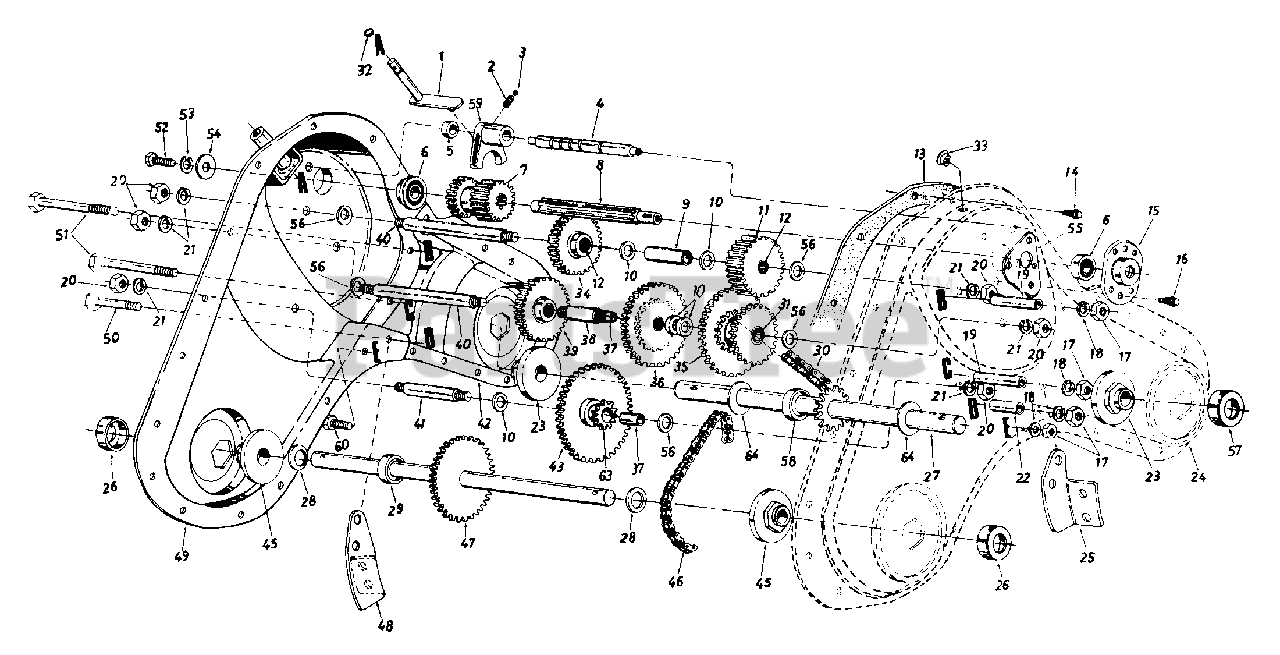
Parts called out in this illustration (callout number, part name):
1	Shifting Bracket Ass'y.
2	Compression Spring .50" Lg.
3	Ball Detent .250" Dia.
4	Detent Shaft 1/2" Dia.
5	Spacer .505" I.D. x .88" O.D.
6	Ball Brg. .62" I.D. x 1.38"
7	Spur Gear 16T (Input)
8	Input Spline Shaft 7/8"
9	Spacer .657" I.D. x 2.85" Lg.
10	Fl-Wash. .640" I.D. x 1.24"
11	Spur Gear 30T 7/8" I.D.
12	Needle Bearing 5/8" I.D.
13	Gasket - Trans. Hsg.
14	Hex S-Tap Scr. 1/4-20 x .5"
15	1-3/8" Dia. Bearing Housing
16	Hex TT-Tap Scr. 1/4-20 x .75"
17	Hex Nut 5/16-18 Thd.
18	L-Wash. 5/16" I.D.
19	Spacer 1.56" Lg.
20	Hex Nut 7/16-20 Thd.
21	Bell-Wash. .45" I.D. x 1.0"
22	Spacer 1.015" Lg.
23	Tine Shaft Brg. 1.002 x 2.50
24	Trans. Housing Ass'y. - L.H.
27	Tine Shaft Ass'y. 1" O.D.
28	Fl-Wash. .76" I.D. x 1.5" O.D.
29	Spacer .75" I.D. x .50" Lg.
30	Chain #50 5/8 Pitch x 52 Links - Endless
31	Needle Bearing 5/8" I.D.
32	Snap Ring
33	Taper Cap Plug
34	Spur Gear 30T 12/16" I.D.
35	30/44T Gear Ass'y. Comp.
36	Spur Gear 44T
37	Sleeve Bearing
38	Gear Hub 3/4" I.D. x 3" Lg.
39	Spur Gear 30T 1.0" I.D. x 1/2" W
40	Jack Shaft 5/8" Dia. x 5"
41	Jack Shaft 5/8" Dia. x 2.38"
42	Trans. Housing Ass'y. - R.H.
43	Spur Gear 55T
45	Wheel Brg. .752" x 2.5"
46	#420 Chain 1/2 Pitch x 50 Links - Endless
47	Wheel Shaft Ass'y. 15.6"
51	Hex Bolt 5/16-18 x 2.5"
52	Hex Bolt 1/4-20 x .62" Lg.
53	L-Wash. 3/8" I.D.
54	Fl-Wash. 1/4" I.D. x .93" O.D.
55	Gear Positioner Bracket
56	Fl-Wash. 7/16" I.D. x 1-3/8"
57	Dust Cover Ass'y. 1" Shaft
58	Spacer 1" I.D. x 2" O.D.
59	Shifting Fork
60	Hex Bolt 5/16-18 x .75" Lg.
63	10T Sprocket Ass'y.
64	Thrust Wash. 1.03" I.D. x 1.62" 0 D.
